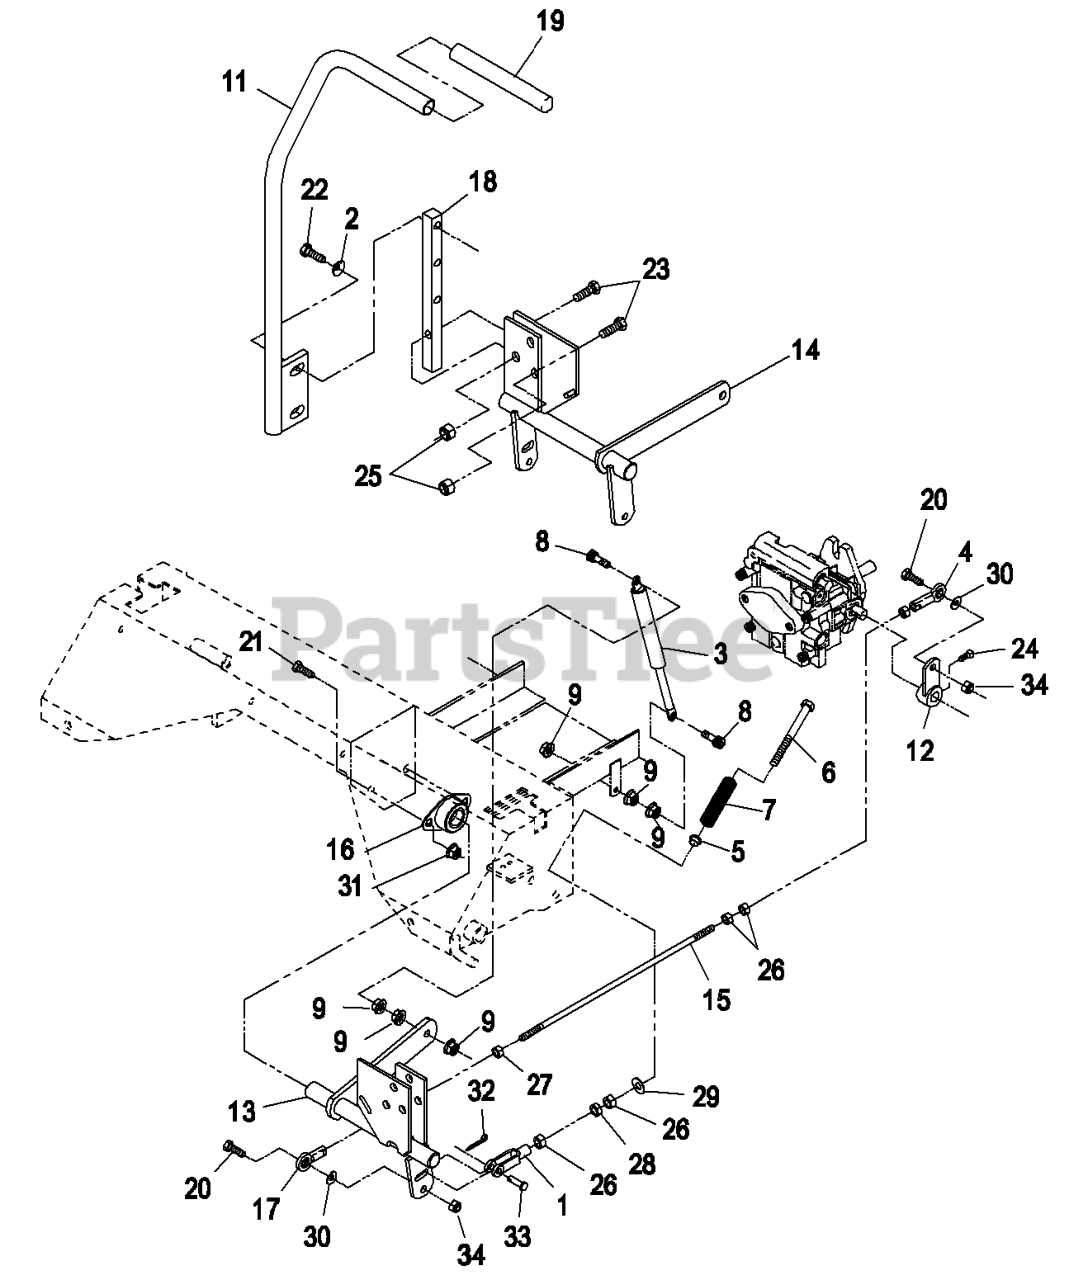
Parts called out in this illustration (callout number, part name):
1	YOKE-ADJUSTABLE
2	WASHER-BELLEVILLE
4	BALLJOINT-RH
5	BUSHING-FLANGED
6	BOLT-RETURN, NEUTRAL
7	SPRING-RETURN, NEUTRAL
8	SCREW-HH
11	RH LEVER ASM
14	CONTROL-MOTION, RH
16	BEARING-FLANGE, SIDE
17	BALLJOINT-LH
18	ARM-SHAFT, CONTROL
19	GRIP-CONTROL, MOTION
20	SCREW-HH
21	SCREW-HH
22	SCREW-HH
23	SCREW-HH
24	SCREW-SET
25	NUT-LOCK, NI
26	NUT-HEX
28	NUT-JAM
29	WASHER-FLAT
30	WASHER-FLAT
31	NUT-HHF, WHIZ
32	PIN-COTTER
33	PIN-CLEVIS
34	NUT-LOCK, NI
